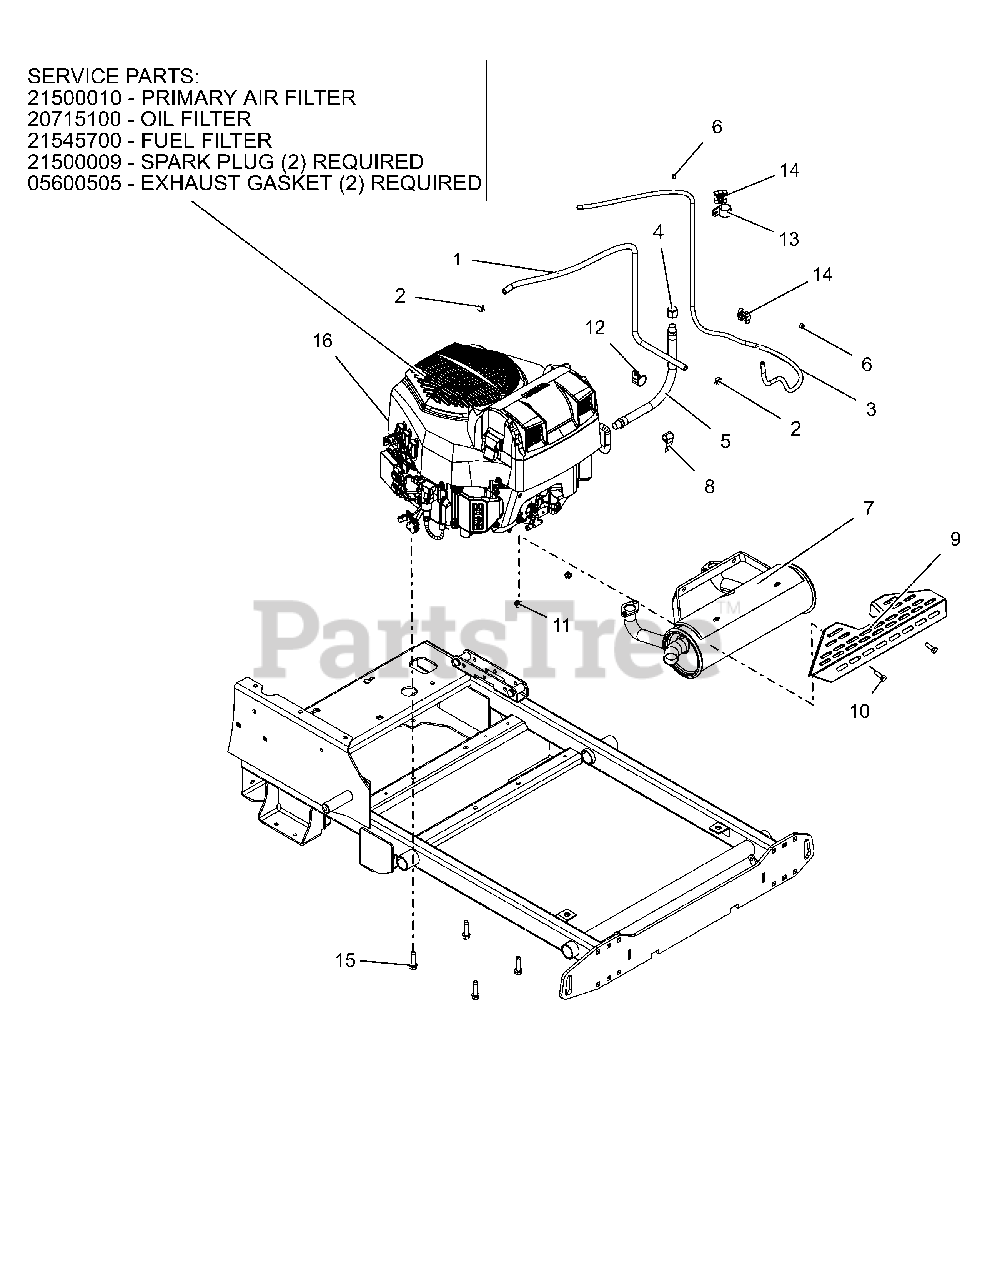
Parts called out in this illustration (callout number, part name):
1	HOSE, .25 LOW-PERM BULK GAS
2	CLAMP, FUEL LINE
3	HOSE, .188 LOW-PERM BULK GAS
4	PIPE CAP 3/8 NPT FEMALE
5	HOSE,HYD .38-14-0K M6N0-M6N0
6	CLAMP-HOSE, SPRING .188
7	MUFFLER, PS KOHLER EFI
9	GUARD, MUFFLER
10	@BLT-HEX .31-18X1.00 GR5 YWZC
11	@NUT-LK-NYL-FLG .31-18 YWZC
12	CLAMP, COUSHIONED STEEL REV
13	CLAMP, COUSHIONED STEEL REV
14	CLIP, T, .38-.50
15	@SCR-TAP .38-16X1.50 HWH TR YZ
16	ENGINE, KOHLER EZT740
16	AIR CLEANER, KOHLER CONFIDANT
16	OIL FILTER KOHLER
16	FILTER-FUEL KOHLER COURAGE PRO
16	PLUG, SPARK KOHLER
16	GASKET, MUFFLER KOHLER TWIN
